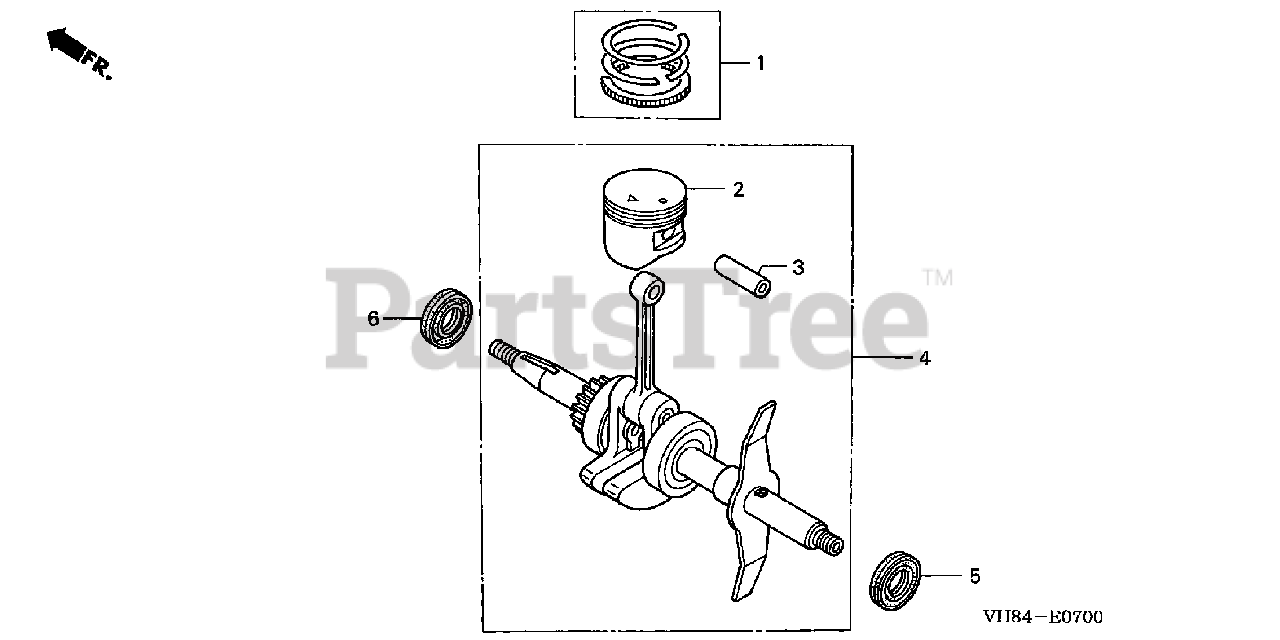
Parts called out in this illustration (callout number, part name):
1	RING SET, PISTON
2	PISTON
3	PIN, PISTON
4	CRANKSHAFT
5	OIL SEAL (12X25X6)
6	OIL SEAL (15X25X6)
